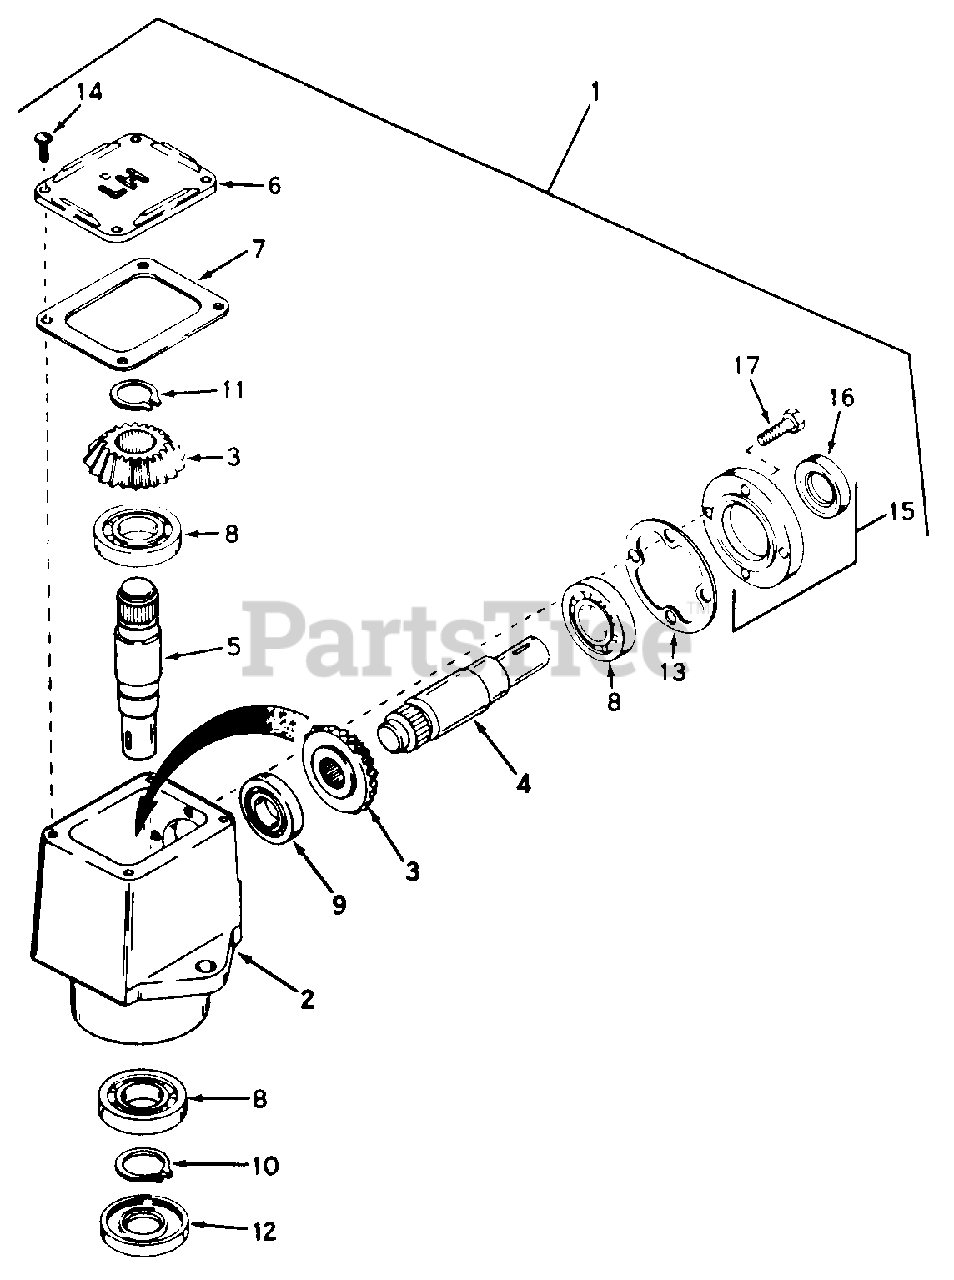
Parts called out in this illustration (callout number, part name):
1	Head Ass'y., Left Hand
2	Housing, Right angle drive
3	Gear, Miter
4	Shaft, Input
5	Shaft, Output
7	Gasket, Cover
8	Bearing, Ball
9	Bearing, Ball
10	Ring, Snap
11	Ring, Snap
12	Seal, Oil
13	Gasket, Cap
14	Screw., Rd. hd. self-tap, 10-24 x 1/2
15	Cap & Seal Ass'y., Retainer
16	Seal, Oil
17	Screw, Hex Hd., 1/4-20 x 1.00" Lg.
